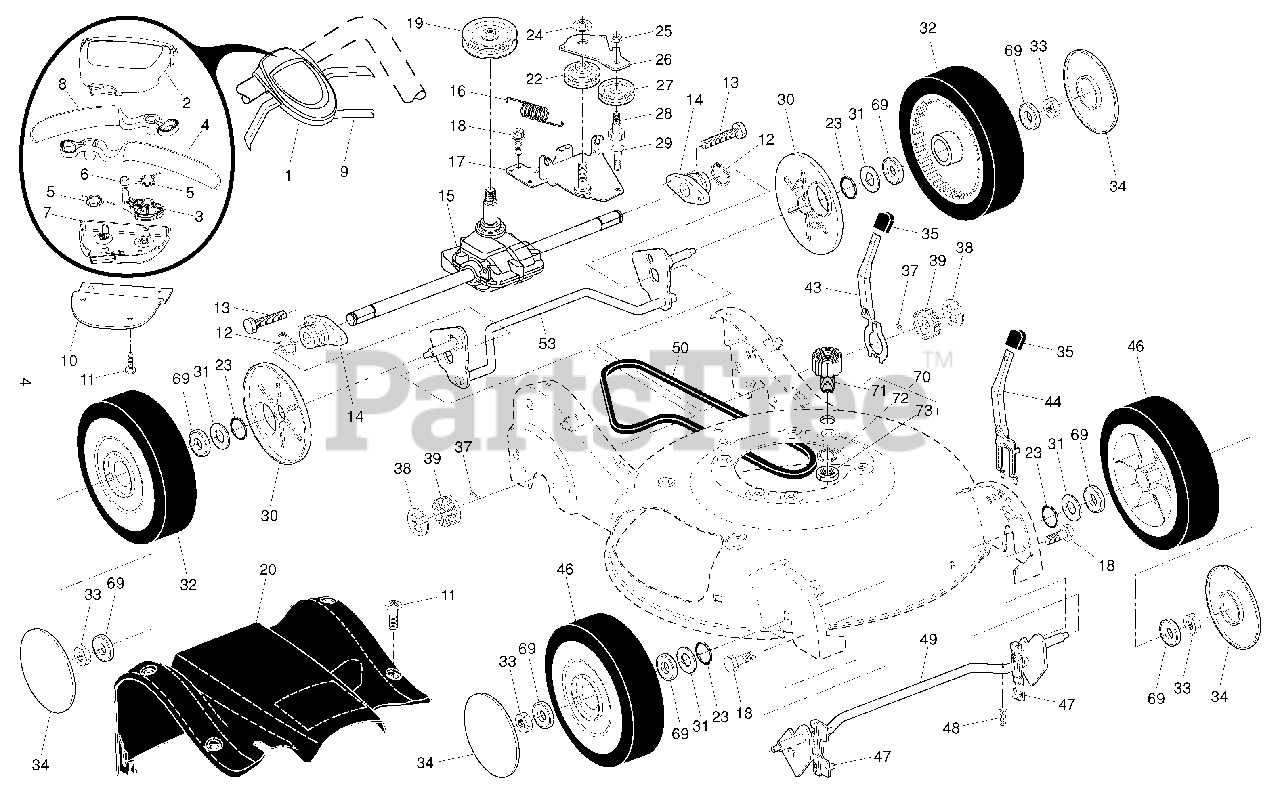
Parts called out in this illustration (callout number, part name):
1	Drive Control Assembly
2	Cover, Drive Control, Top
3	Cam, Drive Control
4	Lever, Drive Control, LH
5	Spring, Drive Control
6	Bushing, Drive Control
7	Cover, Drive Control, Bottom
8	Lever, Drive Control, RH
9	Cable, Drive Control
10	Bracket, Mounting, Drive Control
11	Screw, Torx Head #8 x 5/8
12	Ring, Retaining
14	Bearing / Axle Support
15	Gear Case Assembly, Complete
16	Spring, Return
17	Bracket, Gear Case / Drive Pulley
19	Pulley, Drive
20	Drive Cover Assembly
22	Pulley Assembly, V-Groove
24	Nut, Hex, Flangelock
25	Nut, Hex, Lock
28	Bolt, Hex Head, Shoulder
29	Screw 1/4-20 x 1/16
30	Cover, Dust, Wheel
31	Washer, Flat 3/8
32	Wheel Assembly, Rear 9 x 2-1/4
33	Nut, Hex
43	Lever, Selector, Wheel Height, Rear
44	Lever, Selector, Wheel Height, Front
46	Wheel Assembly, Front 9 x 2-1/4
47	Bushing, Front Axle
48	Retainer, Hairpin Cotter
49	Torque Shaft Assembly, Front
50	Belt, Drive
53	Rear Axle Assembly
69	Bearing, Ball (Wheel)
70	Water Washout Assembly
71	Fitting, Hose, Water Washout
72	Washer, Lock, Internal Tooth
73	Locknut, Hex, with O-Ring
